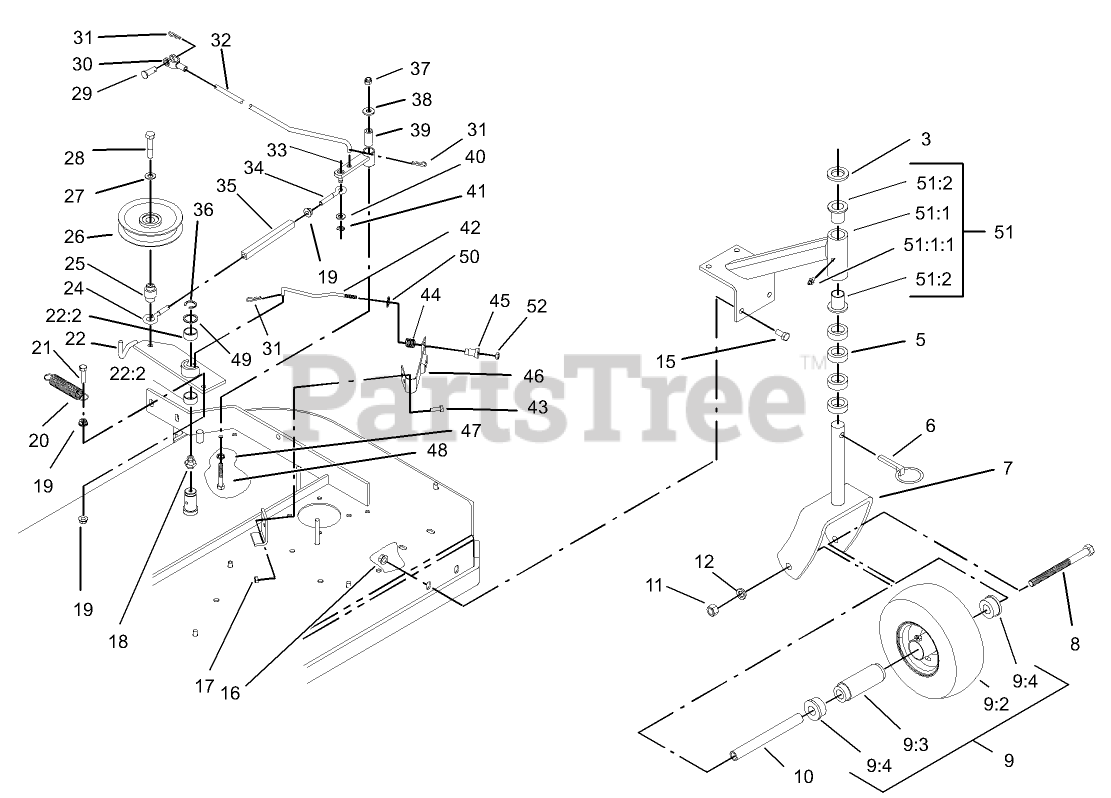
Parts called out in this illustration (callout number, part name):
3	WASHER-FLAT
5	SPACER-CASTER
7	FORK
8	SCREW-HH
9	WHEEL AND TIRE ASM
9:3	BEARING
9:4	BUSHING
10	SPACER
11	NUT-HH
12	WASHER-LOCK
15	SCREW-HH
16	NUT-HHF, WHIZ
17	NUT-LOCK, NI
18	FITTING-GREASE
19	NUT-HF
20	SPRING-EXTENSION
21	SCREW-HH
22	Idler Arm ASM
22:2	SLEEVE-BEARING
24	EYEBOLT-THREAD, LH
25	BUSHING-ENGAGEMENT
26	PULLEY-IDLER
27	WASHER-BELLEVILLE
28	SCREW-HH
29	PIN-CLEVIS
30	YOKE-ADJUSTABLE
31	PIN-COTTER
32	ARM-ASSIST, LINKAGE
33	ARM-ASSIST
34	EYEBOLT-THREAD, RH
35	BODY-TURNBUCKLE
36	RING-RETAINING, EXT
37	NUT-LOCK, NI
38	WASHER-FLAT
39	TUBE-PIVOT
40	WASHER-PLAIN
41	RING-RETAINING, EXT
42	Rod-Brake
43	SCREW-HH
44	SPRING-COMPRESSION
45	SPACER-FLANGED
46	PAD AND SPRING ASM
47	WASHER-SPRING
48	SCREW-HH
49	WASHER-SPINDLE
50	RING-PUSH ON
51	SUPPORT ASM
51:1	Support-Caster
51:1:1	FITTING-GREASE
51:2	BEARING-FLANGED
52	NUT-LOCK, NI
